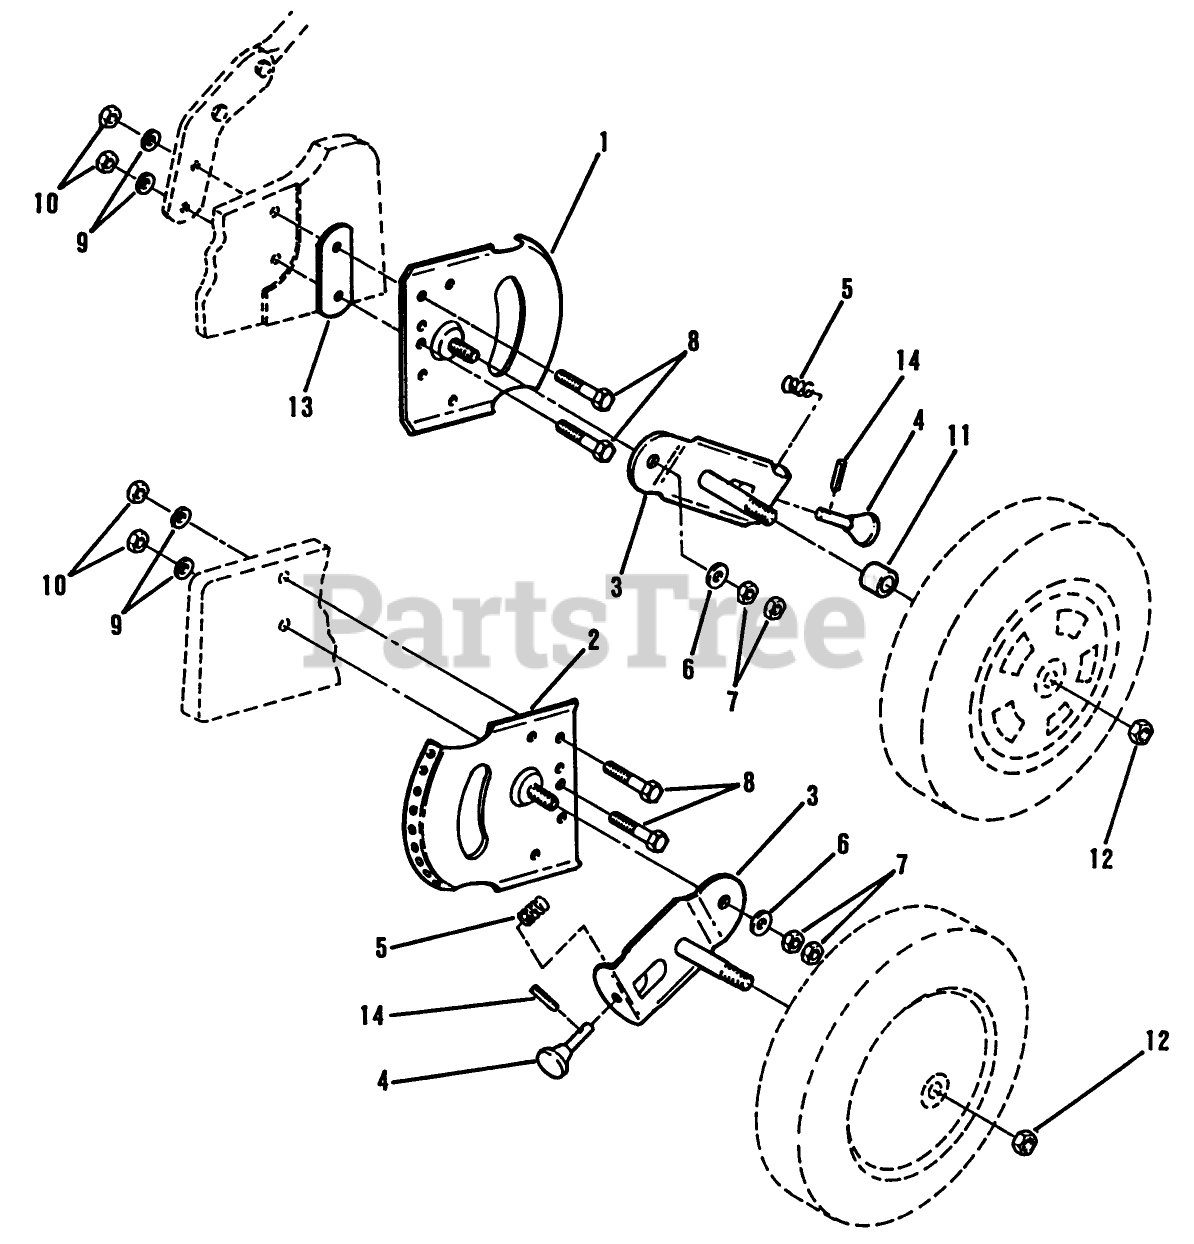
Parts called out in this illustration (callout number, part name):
9	WASHER
10	NUT
14	PIN ROLL
